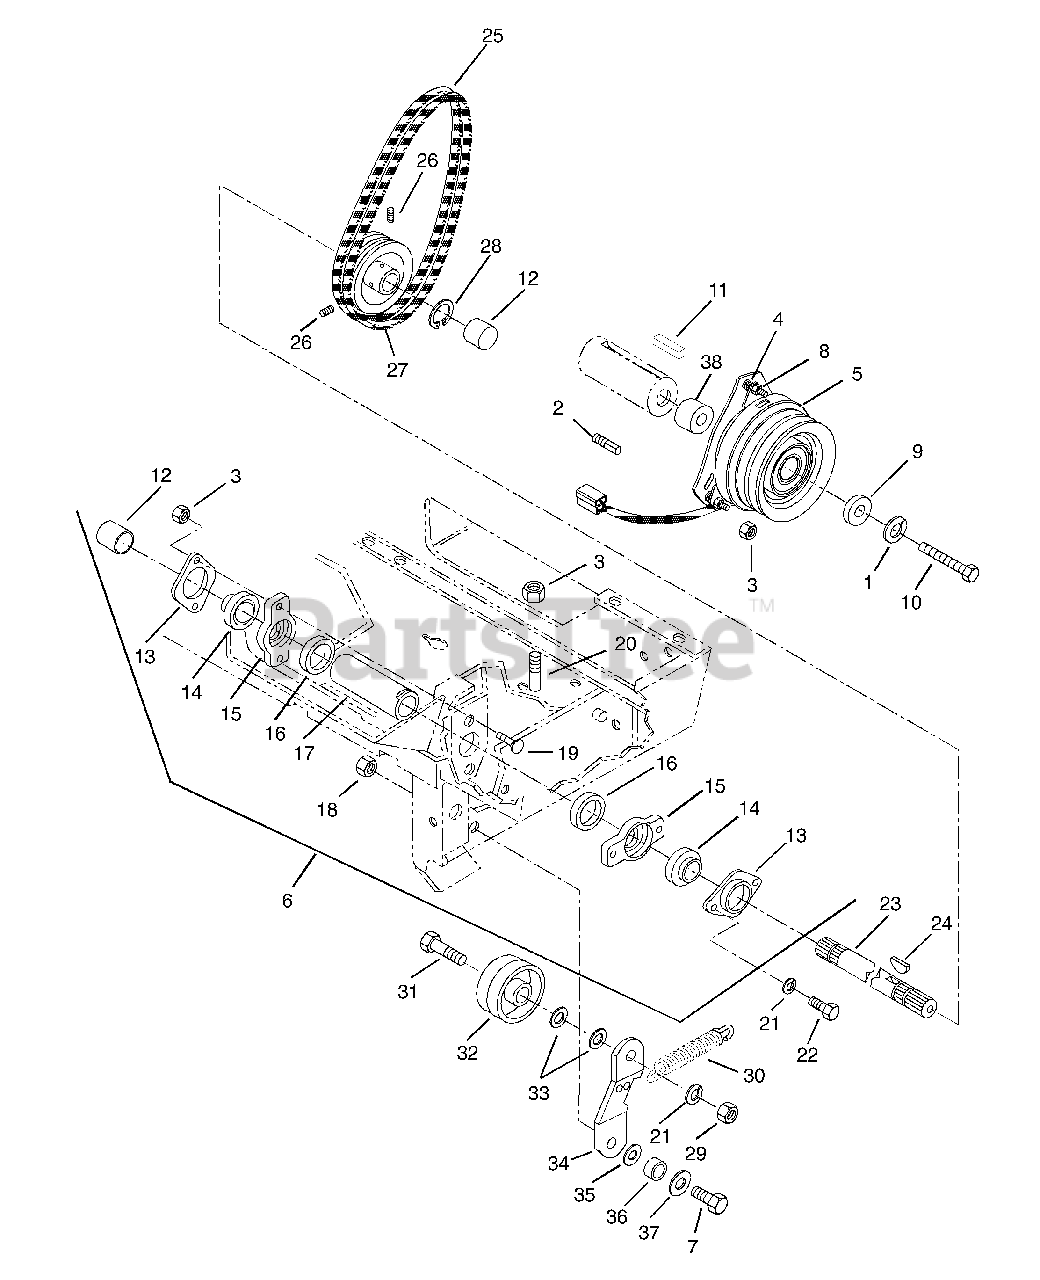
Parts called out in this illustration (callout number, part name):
1	WSHR-LK .438X.133 HVY YWZC
2	STUD - CLUTCH
3	@NUT-LK-CTR .38-16 YWZC
4	SG-COMP WARNER ELEC.
5	CLUTCH-ELEC. WARNER I-5215-62B
6	FRONT PTO KIT
7	@BLT-HEX .50-13X1.25 GR5 YWZC
8	NUT-LK WARNER
9	WSHR-FL-STL .515X1.625X.250 YZ
10	BLT-HEX .44-20X2.00 GR5 YWZC
11	KEY-SQ .25X.625X.25 SAE 8630
12	SHAFT COVER
14	BRG/W COLLAR 1.0 X 2.047 X.844
15	BRG FLANGE
16	BSHG-SLV 1.500X1.750X.560
17	PTO TUBE
18	@NUT-LK-CTR .50-13 YWZC
19	@BLT-RDHDSQNK .38-16X1.50 G2YZ
20	LOCK STUD
21	@WSHR-LK .38X.094 REG YWZC
22	@BLT-HEX .38-16X1.50 GR5 YWZC
23	FRONT PTO SHAFT
24	KEY-FTHR .25X1.25X.25 SAE
25	V-BELT, 4L-WRAPPED (SET)
26	SCR-SET .32-18X.38 SKHCUPNL OH
28	RG-RTNG-EXT 1.00X.042
29	@NUT-HEX .38-16 YWZC
30	SPRING ASSEMBLY
31	@BLT-HEX .38-16X2.00 GR5 YWZC
32	IDLER-FLAT 3.25 X .38 NWHAMSHR
33	WSHR-FL-STL .390X.75X.125 YWZC
34	IDLER ARM
35	SHIM SPACER
36	SPACER .512X.747X.208
37	WSHR-FL-STL .518X2.0X.105 YWZC
38	SPACER, 1.13X1.75X.38
